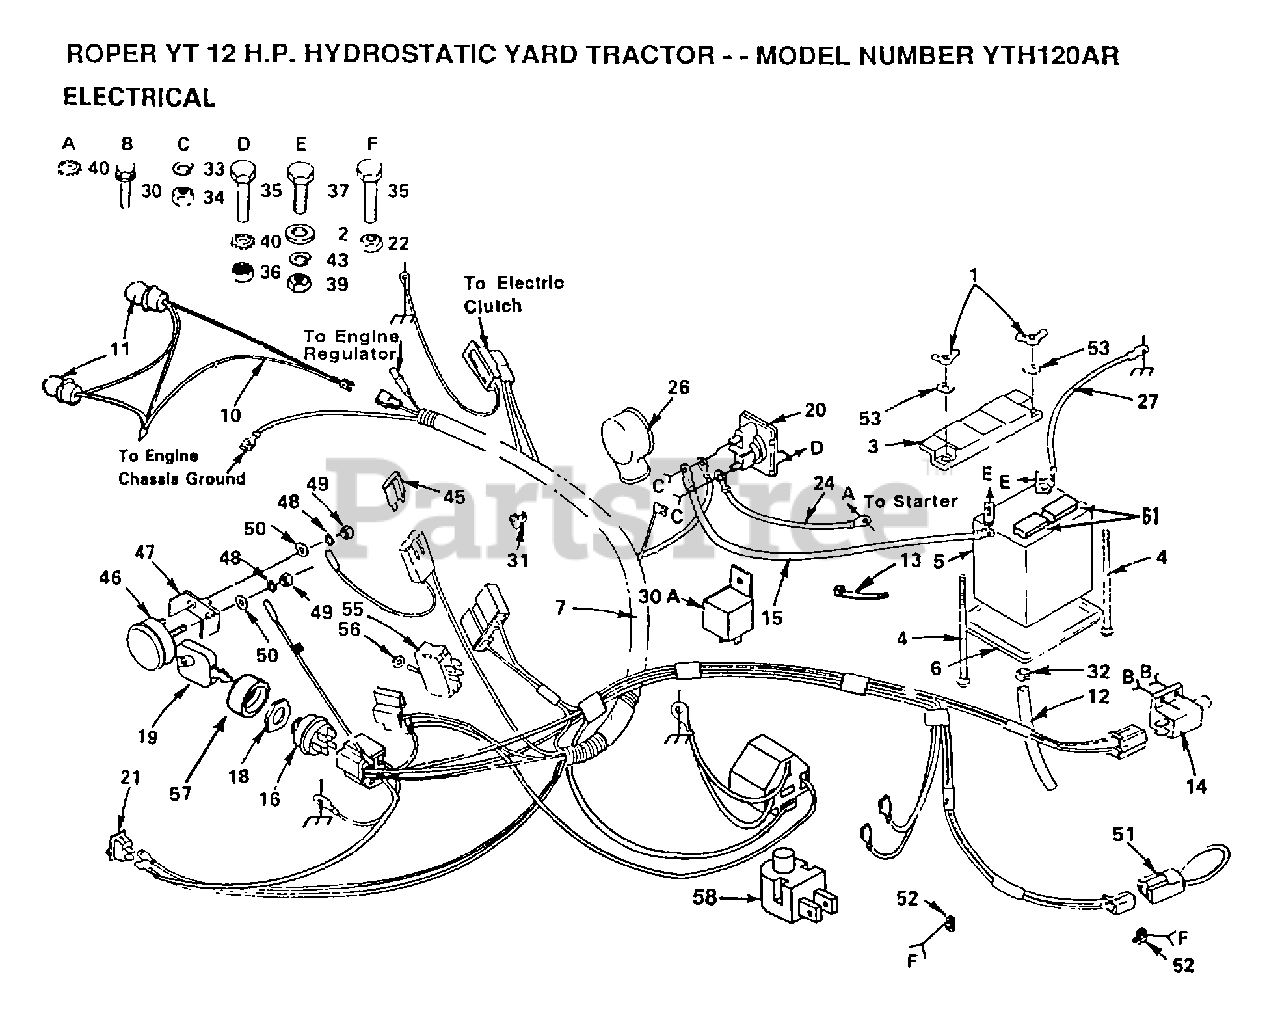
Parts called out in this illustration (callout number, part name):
2	WASHER
4	BOLT
6	"TRAY T, BATTERY"
10	HARNESS T
13	WIRE TIE
14	SWITCH-INTER. GT
15	CABLE-BATTERY T
21	SWITCH LT
27	CABLE T
30	SCREW
30A	RELAY ASSY T
31	CLIP T
32	HOSE CLAMP T
34	NUT
35	BOLT
36	NUT
37	BOLT LT
43	LOCKWASHER
45	FUSE HYT
46	AMMETER T
50	WASHER
52	CLIPT
53	LOCKWASHER GT
55	SWITCH.PTO.T
56	HEX NUT T
58	SWITCH SEAT
61	"CAP,BATTERY "
